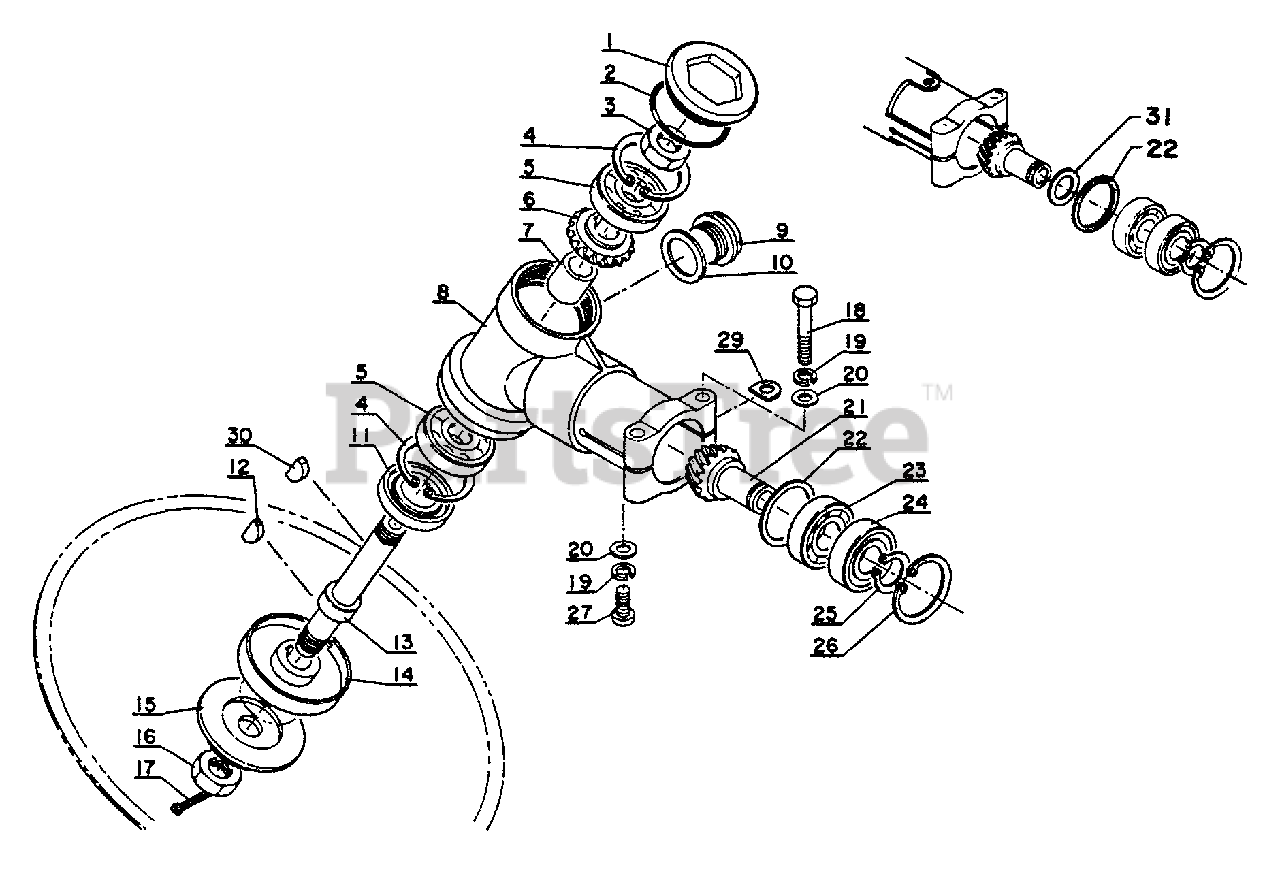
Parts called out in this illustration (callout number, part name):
1	LID, GEAR CASE
2	O-RING - 30
3	NUT - 10
4	RING, RETAINING - 30
5	BEARING, BALL - 6200
6	GEAR SET
7	SPACER
8	CASE, GEAR
9	FITTING, GREASE
10	CASE, GEAR
11	SEAL, OIL
13	DRIVESHAFT
14	ADAPTOR, BLADE - UPPER
15	ADAPTOR, BLADE - LOWER
16	NUT - 10 -- LEFT HAND
17	PIN, SPLIT - 2X22
18	BOLT - 5X30
19	LOCKWASHER - 5
20	WASHER - 5
21	GEAR SET
23	BEARING, BALL - 6001
24	BEARING, BALL - 6001
25	RING, RETAINING - 12
26	RING, RETAINING - 28
27	SCREW - 5X10
